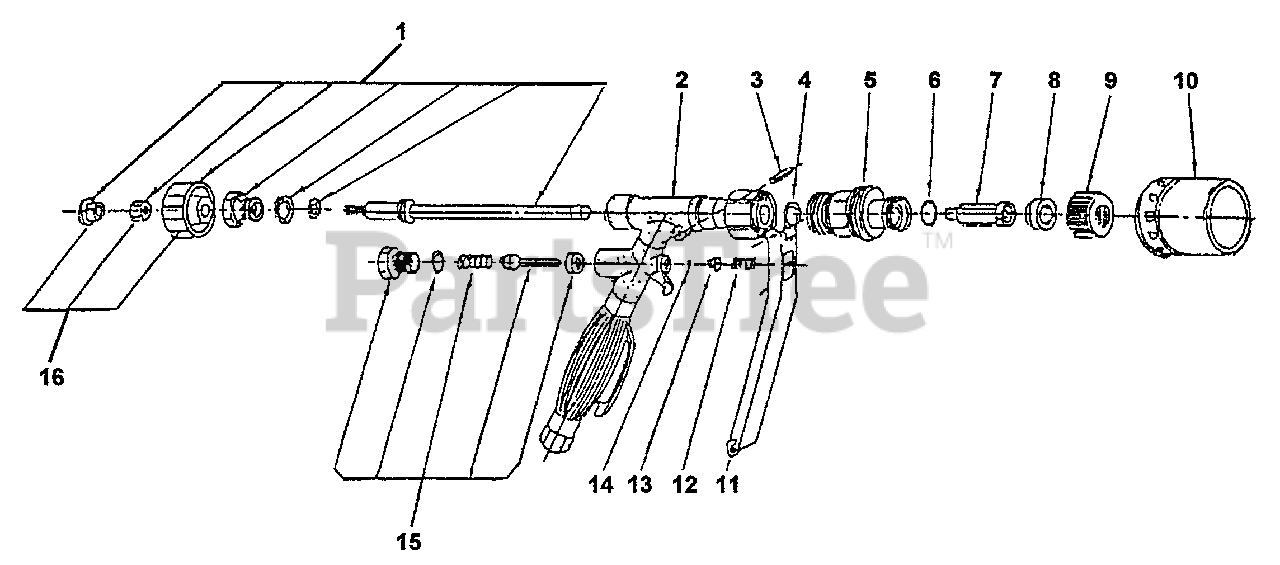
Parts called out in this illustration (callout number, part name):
3	PIN, SPRING 4×20
4	O-RING P-11
5	HOLDER, VALVE
6	O-RING 12 MM
7	ZOOM CORE
8	NOZZLE, PLATE
9	CAP
12	SPRING
14	O-RING 3
15	SHAFT ASSY, VALVE
16	KNOB
